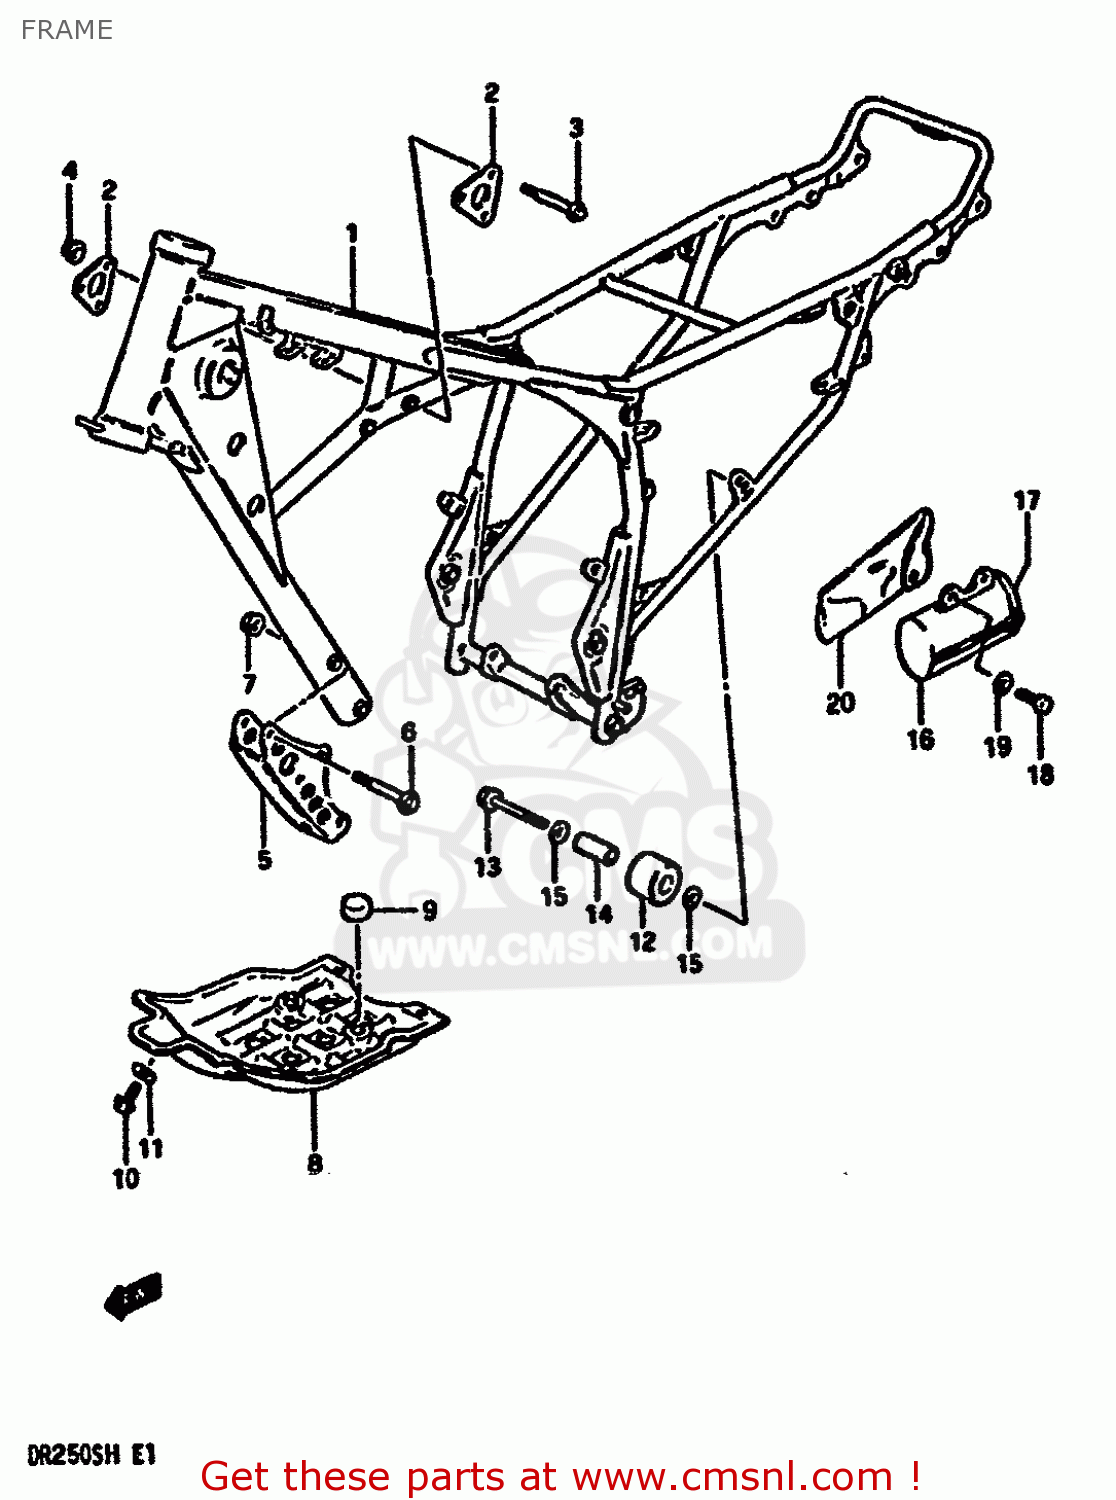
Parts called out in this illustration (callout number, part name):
1	FRAME (BLUE)
2	PLATE,UPPER
3	BOLT(8X50)
4	NUT
5	PLATE,LOWER (BLUE)
6	BOLT 8X67
7	NUT
8	PROTECTOR,ENGINE
9	CUSHION
10	BOLT 6X12
11	WASHER
12	ROLLER,CHAIN LENGTH CONTROL
13	BOLT(8X45)
14	SPACER,CHAIN LENGTH ROLLER
15	WASHER
16	HOLDER,TOOL
17	CAP,HOLDER
18	BOLT 6X16
19	WASHER (6.5X18X1.6)
20	TOOL ASSY
